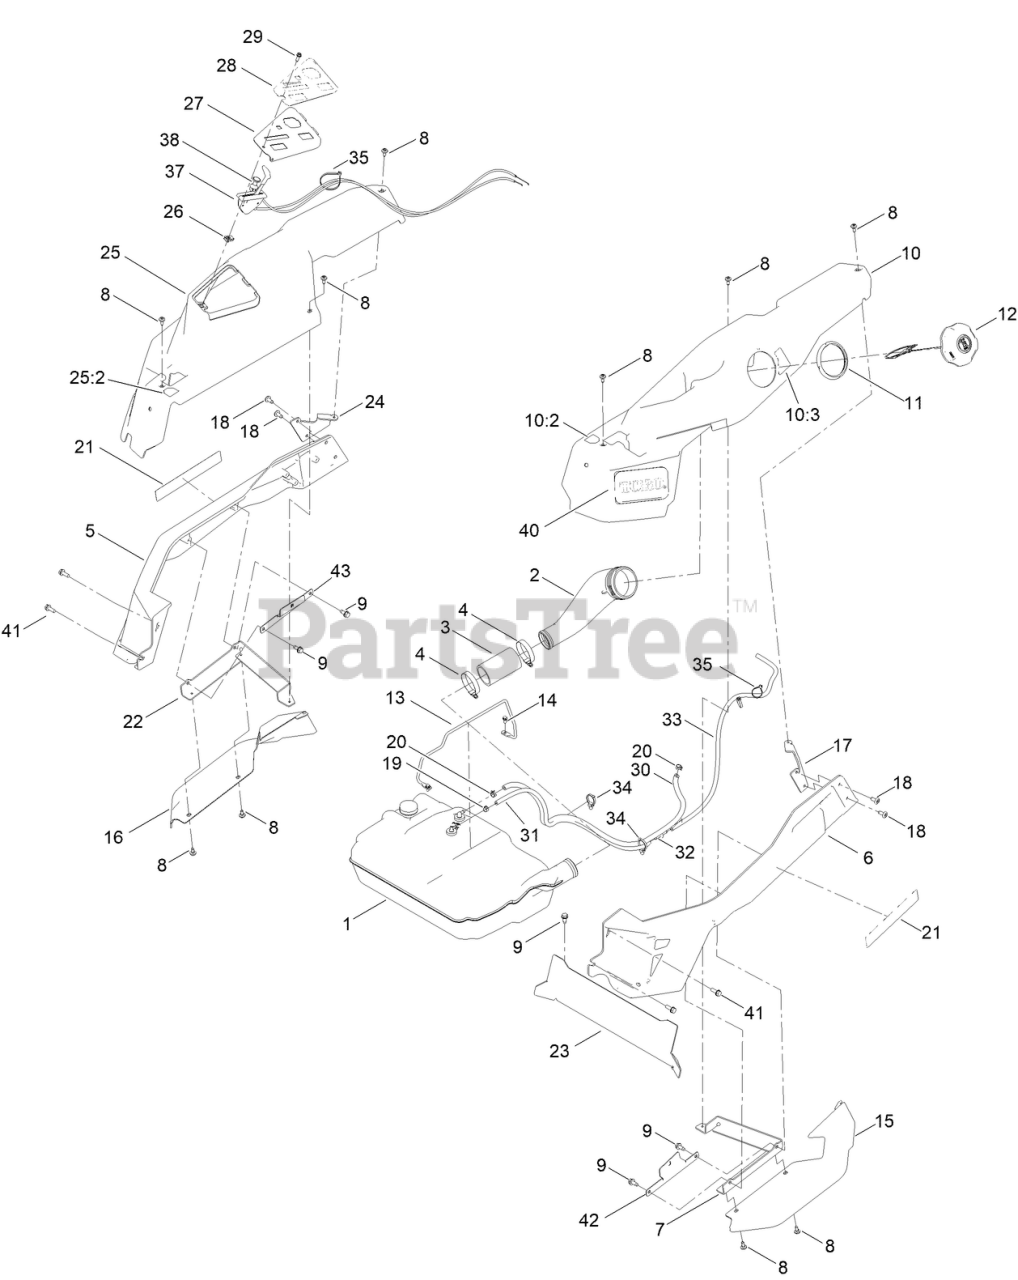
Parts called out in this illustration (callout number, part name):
1	TANK ASM - FUEL
2	NECK-FILLER, FUEL
3	HOSE-FILLER, FUEL
4	CLAMP-HOSE
5	CAST-TUBE, RH [RED]
6	CAST-TUBE, LH [RED]
7	MOUNT-POD BRACKET LH
8	SCREW-SHOULDER
9	SCREW-HWHTF
10	POD ASM - LH W/DECALS
10:2	DECAL-CONTROL LEVER, LH
10:3	DECAL-FUEL FILL
11	RING-RETAINING
12	CAP-FUEL, RATCHETING
13	ROD-HOLD DOWN
14	SCREW-HWH
15	FENDER-TIME CUTTER, LH
16	FENDER-TIME CUTTER, RH
17	BRACKET-REAR POD, LH
19	CLAMP-HOSE
20	CLAMP-HOSE
21	DECAL-TITAN
22	MOUNT-POD BRACKET RH
23	PLATE-KICK
24	MOUNT-POD BRACKET RH
25	POD ASM - RH W/DECALS
25:2	DECAL-CONTROL LEVER, RH
27	PANEL-CONTROL
28	DECAL - CONTROL PANEL
29	SCREW-HWHTF
30	HOSE-FUEL
31	HOSE-FUEL
32	ADAPTER ORIFICE
33	HOSE-LP
34	CLIP-TIE
35	TIE-CABLE
37	CABLE-THROTTLE
38	CABLE-CHOKE
40	DECAL - TORO LOGO
41	SCREW-TAPTITE
42	BRACKET-ALIGNMENT, POD LH
43	BRACKET- ALIGNMENT, POD RH
